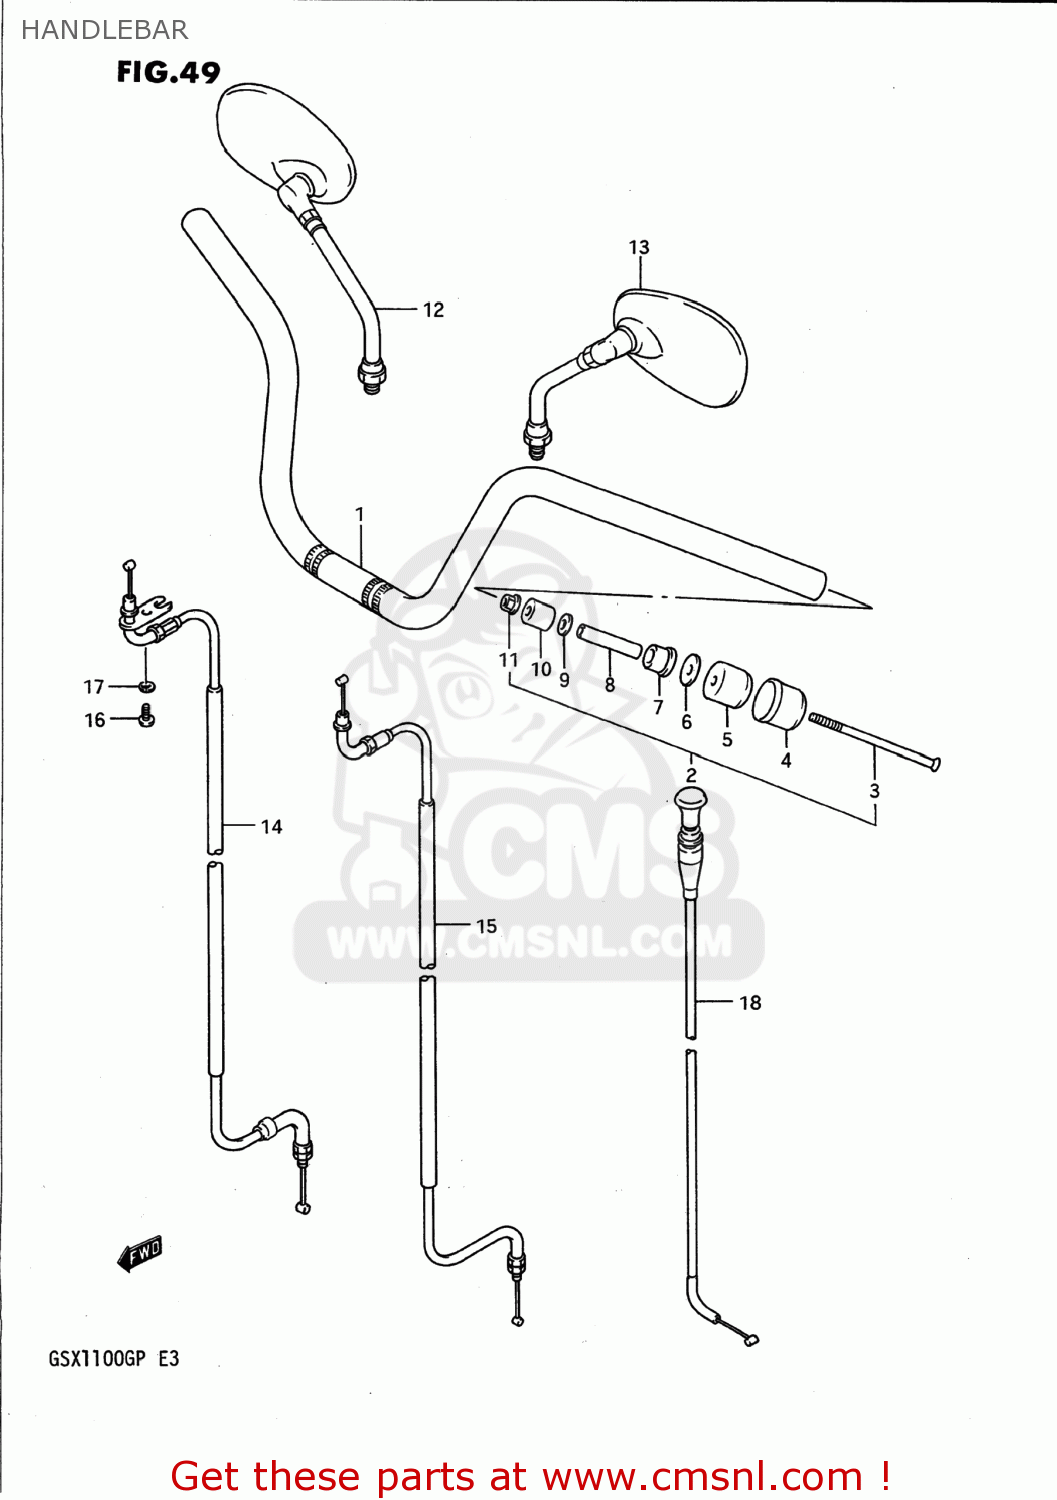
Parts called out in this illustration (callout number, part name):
1	HANDLEBAR,RIGHT
2	BALANCER SET,HANDLEBAR
3	SCREW(6X110)
4	CAP,HANDLE BALANCER
5	BALANCER,HANDLEBAR
6	SPACER,BALANCER
7	EXPANDER,HANDLE BALANCER
8	SPACER,EXPANDER
9	WASHER(6.5X18X1)
10	BALANCER,HANDLEBAR
11	NUT
12	MIRROR ASSEMBLY,REAR VIEW
13	MIRROR ASSEMBLY,REAR VIEW
14	CABLE ASSEMBLY,THROTTLE
15	CABLE ASSEMBLY,THROTTLE
16	SCREW
17	LOCK WASHER
18	CABLE ASSEMBLY,STARTER
